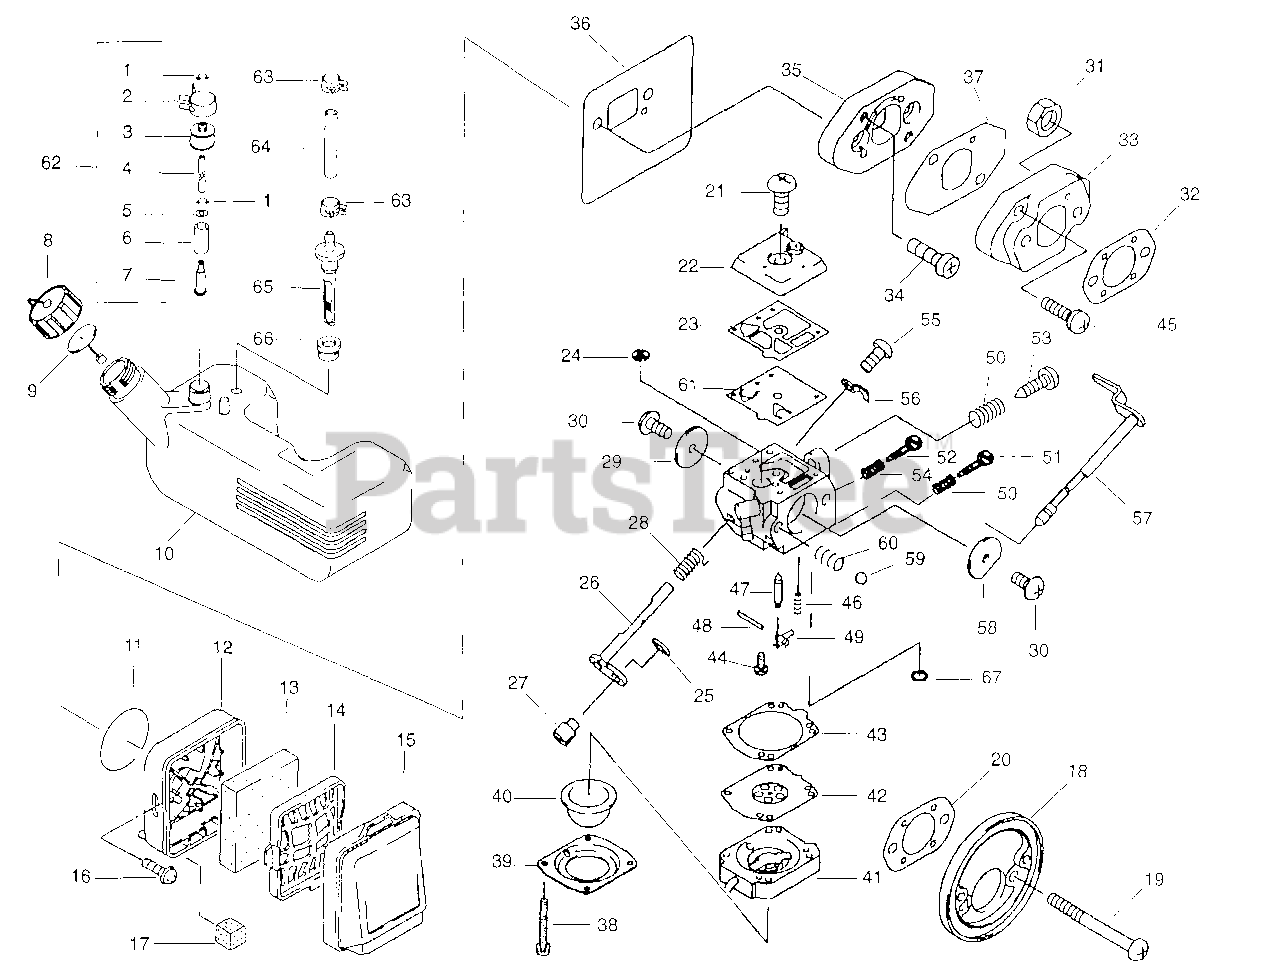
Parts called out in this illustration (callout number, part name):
8	Tank Cap Type 1
8	Tank Cap Type 2
9	Breather
10	Fuel Tank Type 1
10	Fuel Tank Type 2
11	O-Ring
12	Filter Case
16	Screw
21	Screw Type 1
21	Screw Type 2
25	Ring - Snap
27	Adjuster
29	Valve - Throttle Type 1
29	Valve - Throttle Type 2
33	Insulator
34	Screw
38	Screw Type 1
39	Cover Type 1
39	Cover Type 2
41	Primer Base Type 1
41	Primer Base Type 2
42	Diaphragm Type 1
42	Diaphragm Type 2
43	Gasket Type 1
43	Gasket Type 2
47	Valve - Float
49	Arm - Float
50	Spring-Type 1
51	Needle - Type 1
52	Screw Type 1
52	Screw Type 2
53	Needle - Type 1
57	Shaft Assy
58	Valve - Choke
61	Diaphragm Pump
62	Filter Ass'y.
67	O-Ring - Type 2
